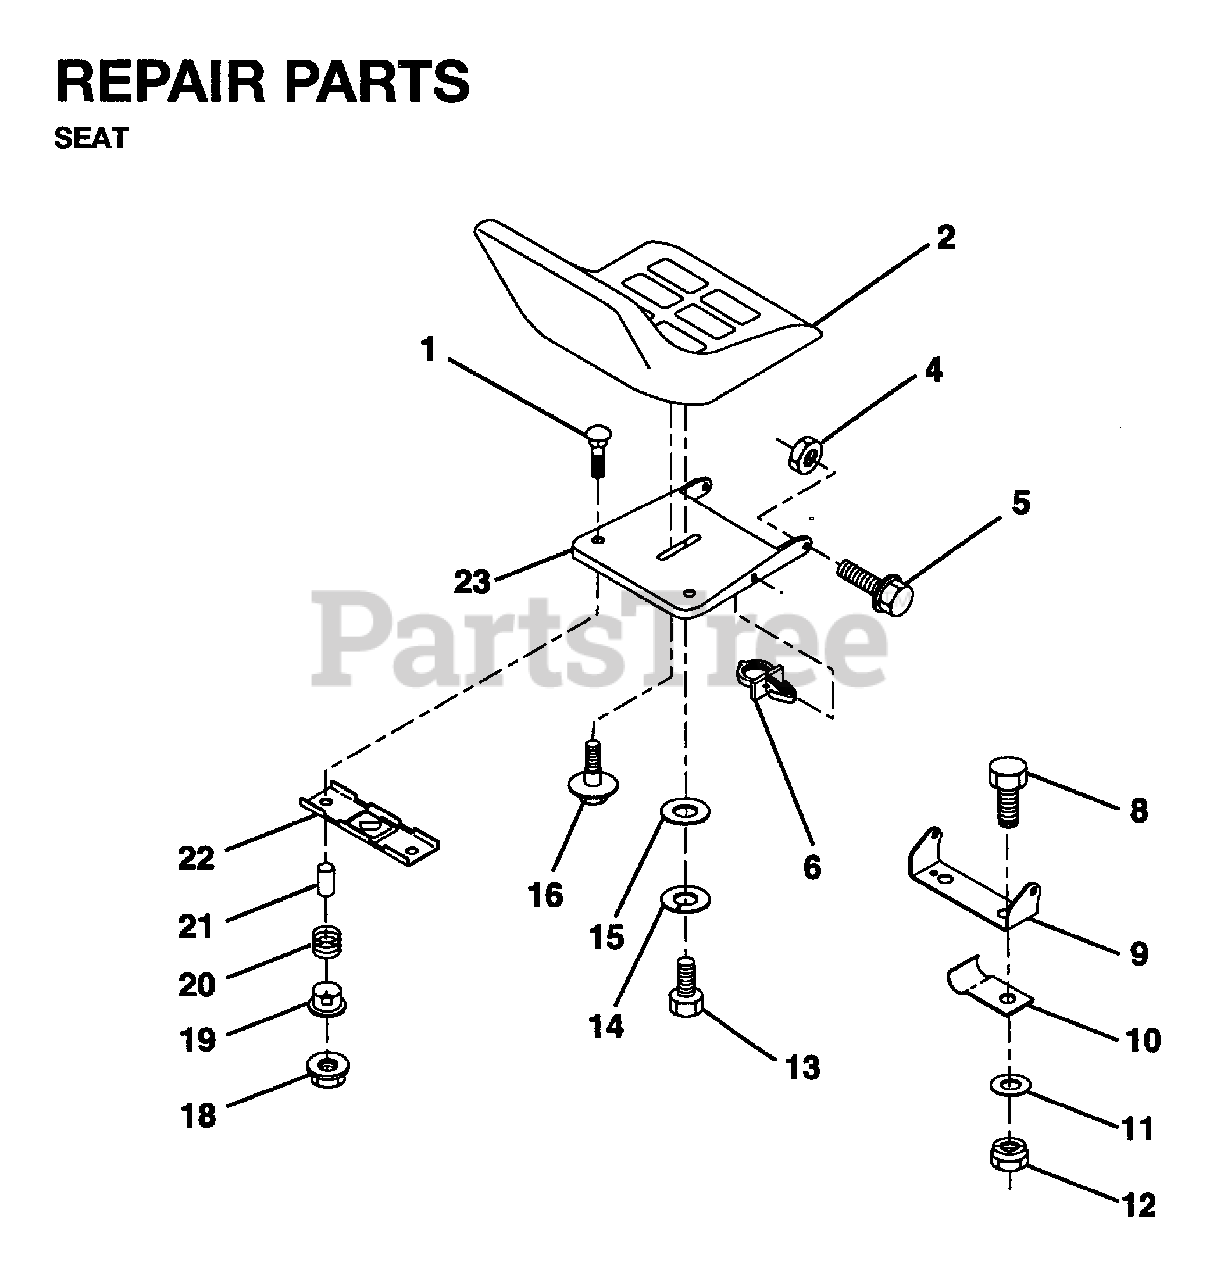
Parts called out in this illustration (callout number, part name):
1	BOLT CARRIAGE 1/4-20X1 3/8
2	SEAT
4	NUT.71038.31-18.HEX.NYLOCK
6	PUSH CLIP
9	SEAT PIVOT BRKT
10	CLIP,INSULATOR
11	WASHER 12/32X2X10GA
12	LOCKNUT
13	BOLT
14	LOCKWASHER
16	BOLT,SHOULD
18	NUT.CROWNLOCK.1/4
21	SPACER SPLIT 28X.96
22	BRKT SWITCH
23	SEAT PAN
